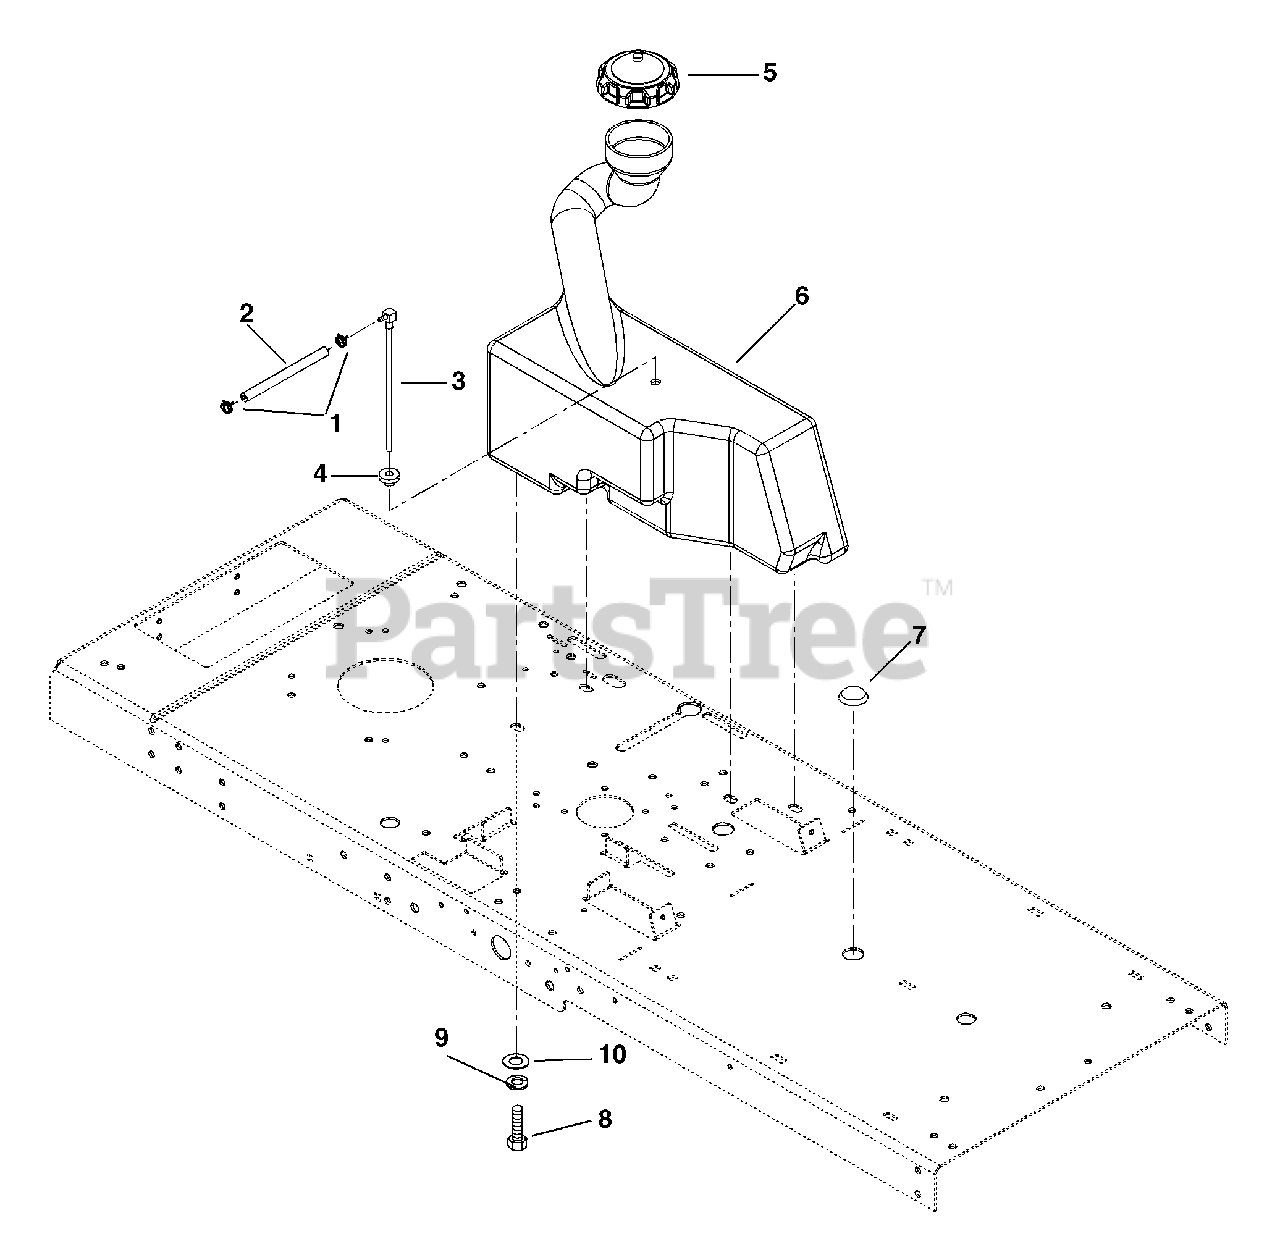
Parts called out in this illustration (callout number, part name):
1	Clamp-Hose-Wire .490/.510 x .116
2	Hose-Fuel .25 I.D. x 17.5"Long
3	Fitting-Tank
4	Bushing
5	Cap-Fuel
6	Fuel-Tank
7	Plug-Button
8	Bolt-Hex .312-18 x .75 Grade 5
9	Washer-Lock .31 x .078
10	Washer-Flat-Steel .38 x .875 x .083
